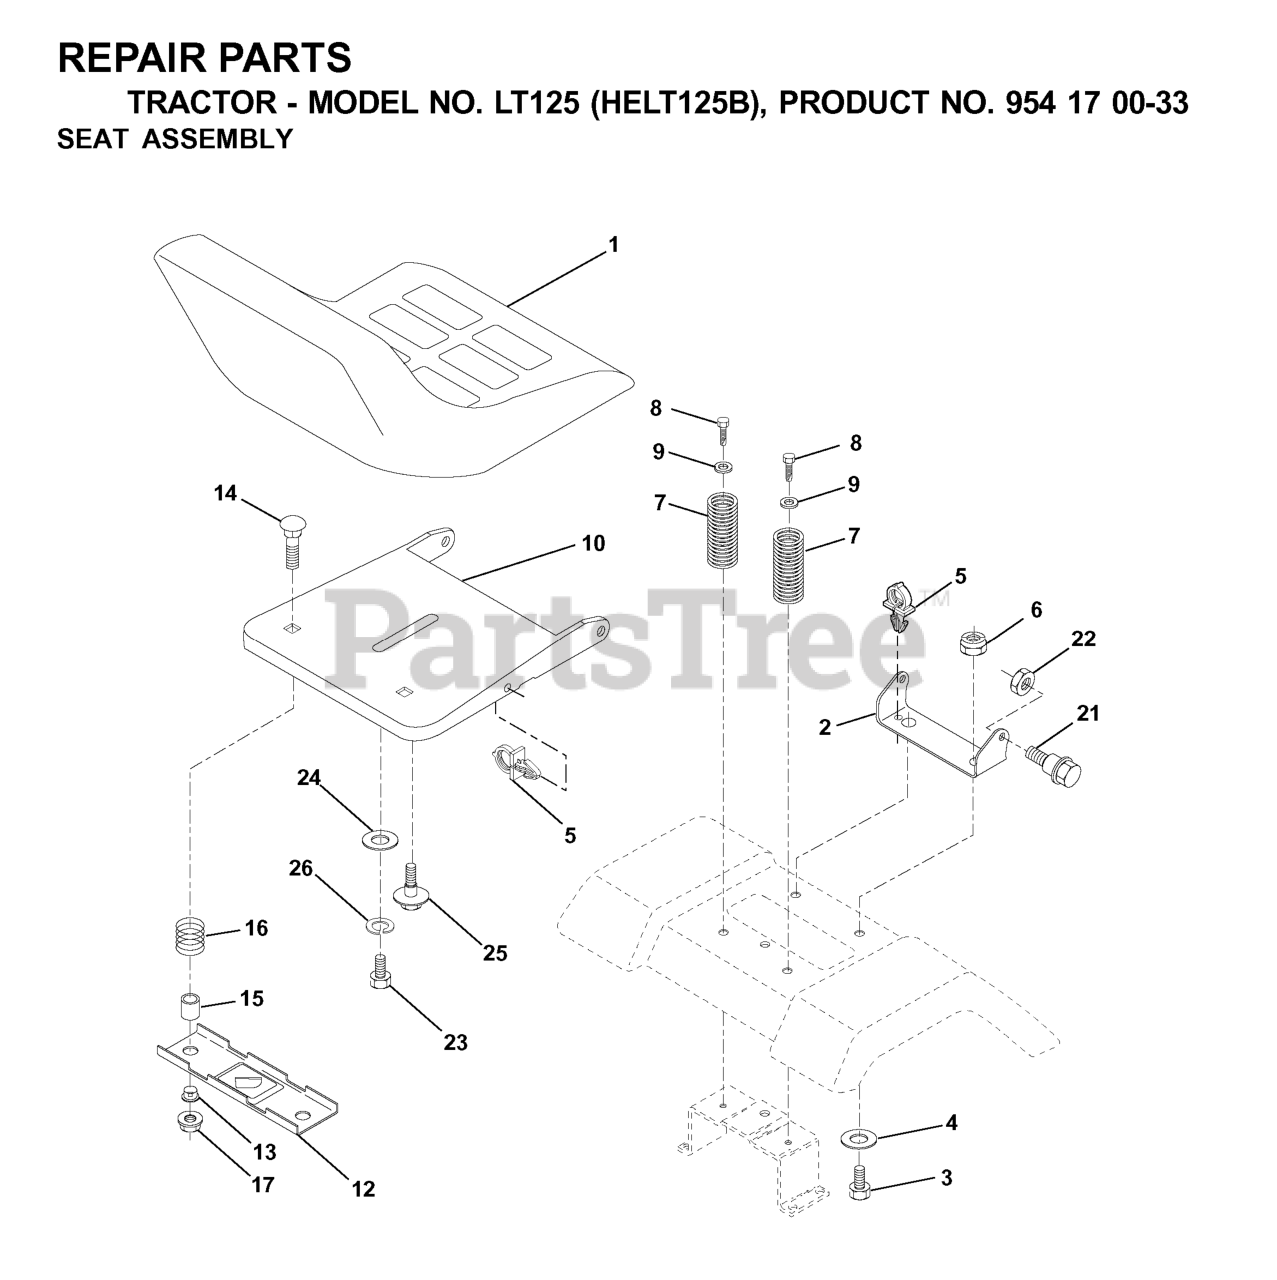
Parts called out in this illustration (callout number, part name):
1	SEAT
2	SEAT PIVOT BRKT
3	BOLT, HEX 3/8-16X1
6	NUT
7	SPRING COMPRESSION
8	SCREW 3/8-16X1
9	WASHER
10	PAN, SEAT
12	BRKT SWITCH
14	BOLT.ROUND.HEAD.SQUARE.NECK
15	SPACER SPLIT 28X.96
17	NUT T
21	BOLT.SHOULDER.5/16-18
22	NUT.71038.31-18.HEX.NYLOCK
23	BOLT.HEX.BLACK
24	WASHER GT
25	BOLT,SHOULD
26	LOCKWASHER
